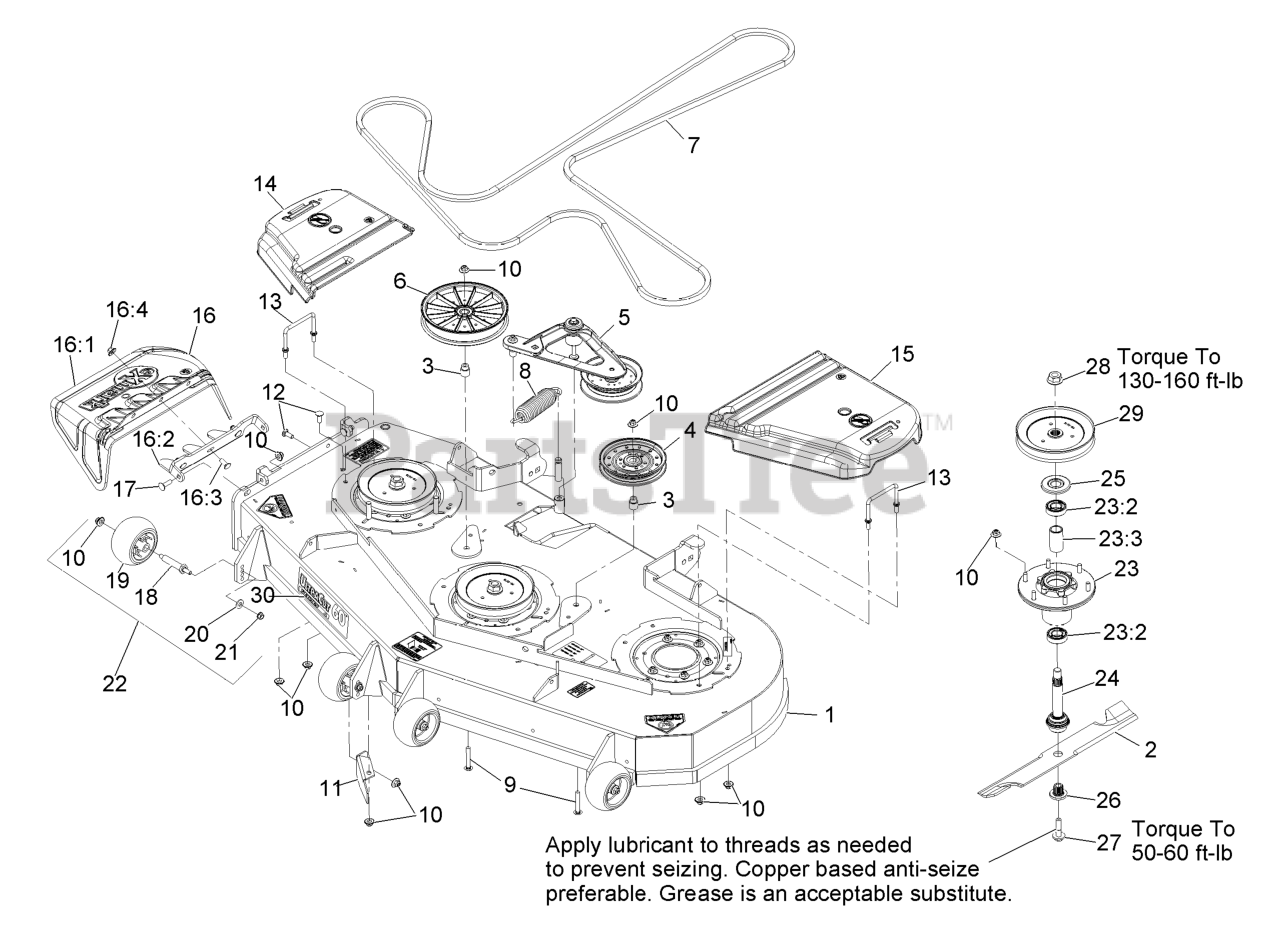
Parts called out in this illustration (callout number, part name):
1	DECK ASM,W/DECALS 60
3	BUSHING-IDLER
5	DECK IDLER ASM
6	PULLEY,IDLER 8"FLAT
7	BELT,V-5V-198.75
9	SCREW-CARR
10	Nut-Nyloc 3/8-16 Flg
11	BAFFLE,DISCHARGE 52/60
12	SCREW-CARR
13	WIREFORM-COVER
14	COVER-BELT, RH
15	COVER-BELT, LH
16	ASM,DISCHARGE CHUTE
16:1	CHUTE,DISCHARGE
16:2	BRACKET,DISCHARGE CHUTE
16:3	SCREW-CARR
16:4	Nut-Nyloc 3/8-16 Flg
17	Bolt-Carriage 3/8-16 X 1 1/4
19	ROLLER-SCALP, ANTI
20	WASHER-BELLEVILLE
21	NUT-HHF, WHIZ
23	ASM-CUTTER HSG WITH BEARINGS
23:2	BEARING-BALL
23:3	SPACER-BEARING
24	ASM-SPINDLE AND SEAL
25	GUARD,BEARING TOP .989
26	BUSHING,SPLINED
27	SCREW,SEMS 1/2-20 X 2.19
28	NUT-FLANGE
29	SHEAVE,BLADE DRIVE 7.25
30	DECAL,ULTRACUT 60 SERIES
